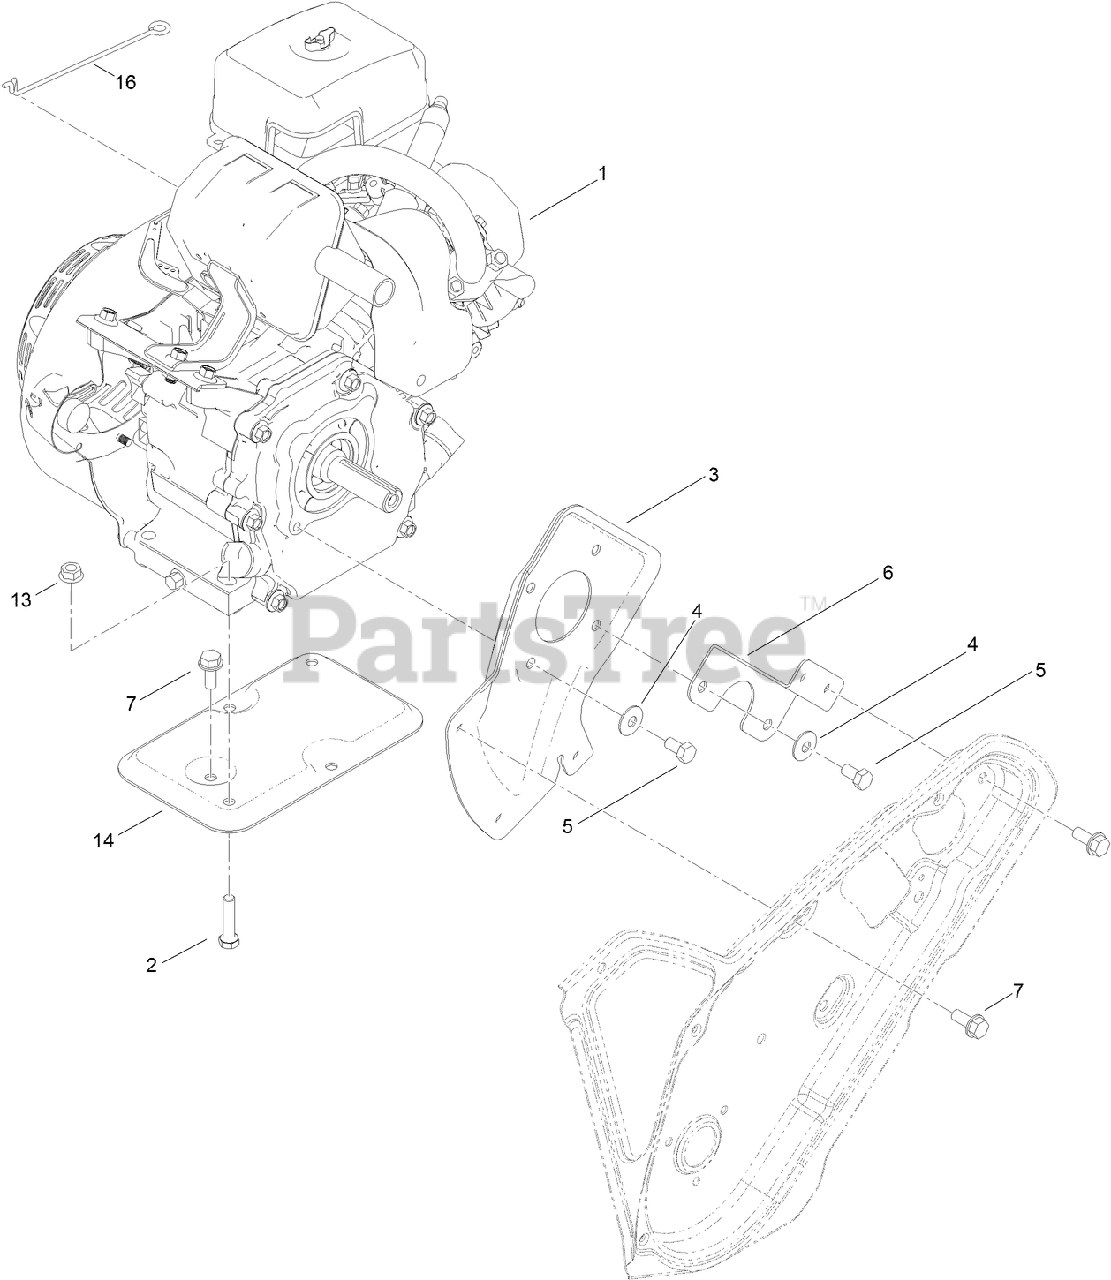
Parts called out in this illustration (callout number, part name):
1	ENGINE-LC168FS-1
2	SCREW-HH
3	PLATE-ENGINE, PTO
4	WASHER-BELLEVILLE
5	SCREW-HH
6	SUPPORT-ENGINE, SIDE
7	SCREW-HWHTF
13	NUT-HF
14	SUPPORT-ENGINE
16	LINK-KNOB, CHOKE
